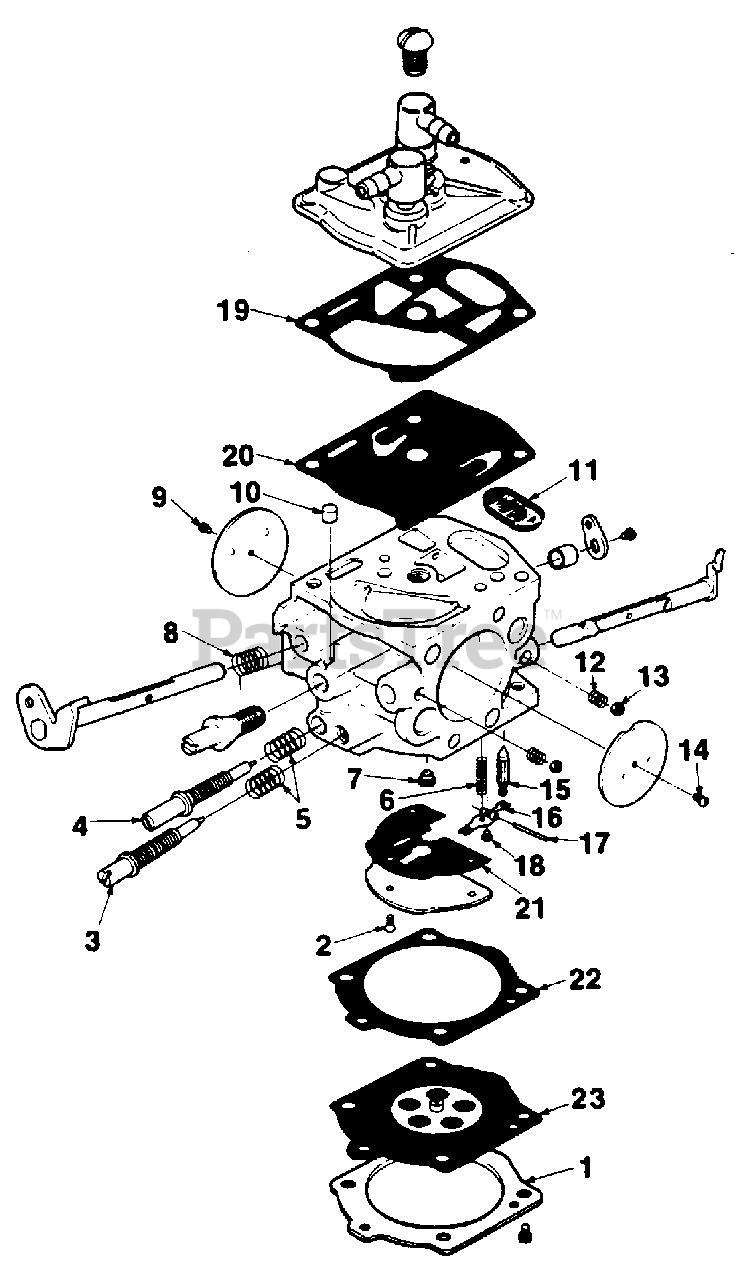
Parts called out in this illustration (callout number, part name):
1	Repair Kit
2	Repair Kit
3	Repair Kit
4	Repair Kit
5	Repair Kit
6	Repair Kit
7	Repair Kit
8	Repair Kit
9	Repair Kit
10	Repair Kit
11	Repair Kit
12	Repair Kit
13	Repair Kit
14	Repair Kit
15	Repair Kit
16	Repair Kit
17	Repair Kit
18	Repair Kit
19	Repair Kit
20	Repair Kit
21	Repair Kit
22	Repair Kit
23	Repair Kit
